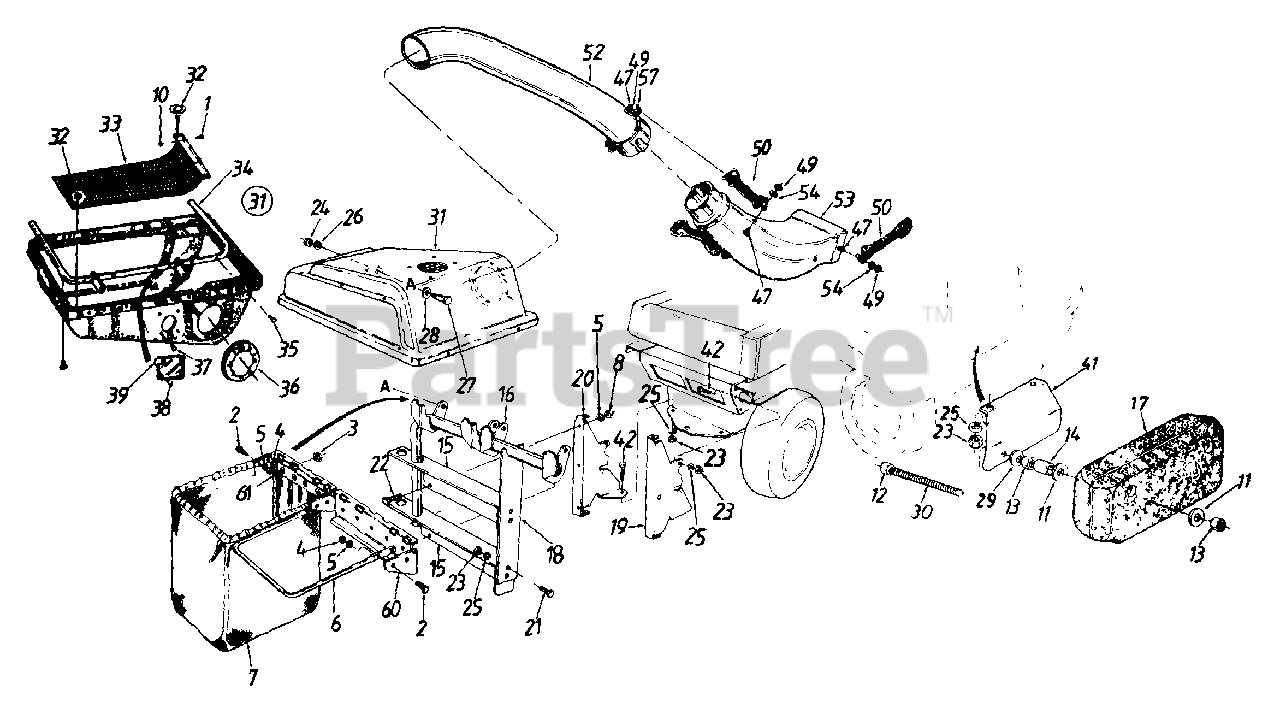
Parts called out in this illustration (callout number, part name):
1	Pop Rivet .188 Dia.
2	Hex Bolt 1/4-28 x .88"
3	Hex Sems Nut #10-24 Thd.
4	Hex Nut 1/4-28 Thd.
5	L-Wash. 1/4" I.D.
7	Grass Catcher Bag
8	Hex Nut 1/4-20 Thd.
10	Flat Wash. 1/4" I.D.
11	Fl-Wash..45" I.D.
12	Hex L-Nut 7/16-14 Thd.
13	Hex Nut 7/16-14 Thd.
14	Spacer
17	Front Counterweight
19	Grass Catcher Suppt. Brkt.-R.H.
20	Grass Catcher Suppt. Brkt.-L.H.
21	Hex Bolt 5/16-18 x .75"
22	Hex Bolt 1/4-20 x .62" - Gr. 5
23	Hex Nut 5/16-18 Thd.
24	Hex Nut 3/8-16 Thd.
25	L-Wash. 5/16" I.D.
26	L-Wash. 3/8" I.D.
27	Shld. Bolt 3/8-16 x .50" Dia.
28	Bell-Wash..505" 1.0. x 1.0" O.D.
29	Bell-Wash. 7/16" I.D.
30	Stud 7/16-14 x 5-5/8" Lg.
31	Grass Catcher Cover Ass'y.
32	Twist Fastener
35	Hex AB-Tap Scr. 1/4 x .62"
36	Seal - 7"
37	Truss B-Tap Scr. #10 x .5" Lg.
38	Plastic Plate
39	Speed Nut
47	Hex Bolt 1/4-20 x .625"
49	Hex Ins. L-Nut 1/4-20 Thd.
50	Retainer Strap Ass'y.
52	Catcher Tube
53	Discharge Chute
54	L-Wash..27" I.D.
57	Retainer Hook Brkt.
61	Truss Mach. Scr. #10-24 x .5"
